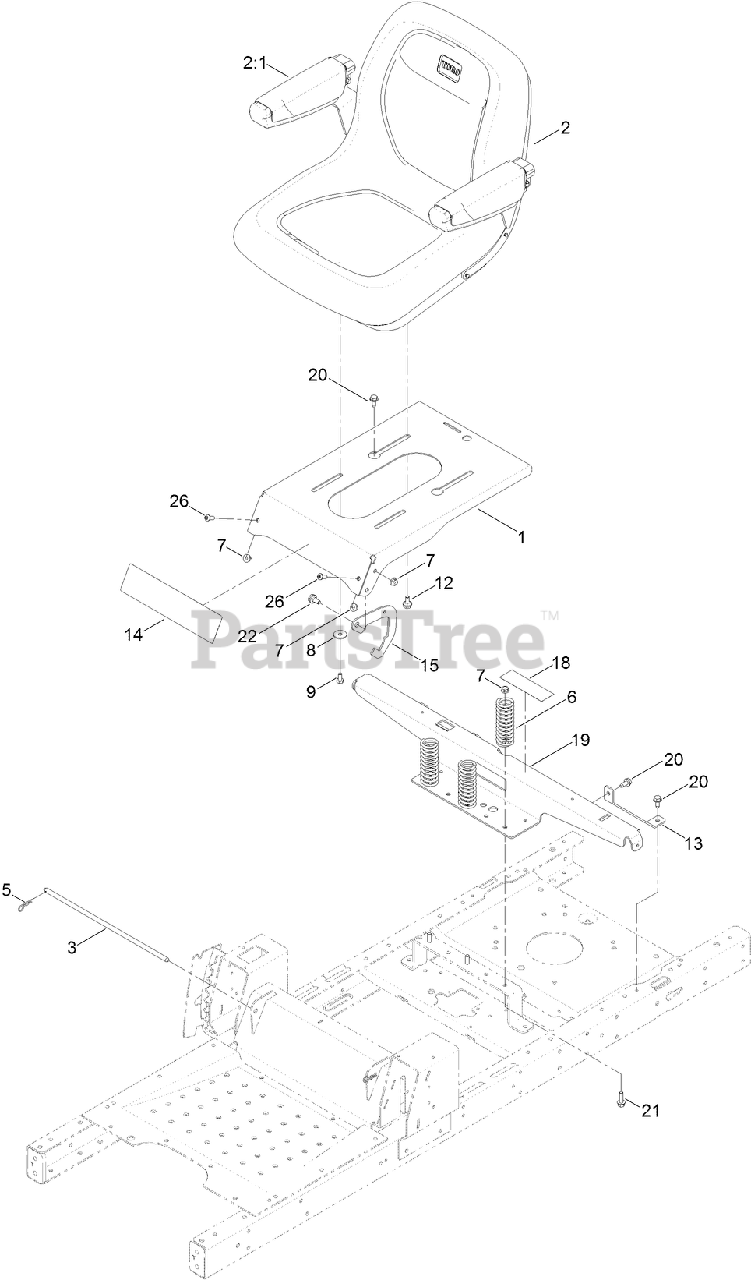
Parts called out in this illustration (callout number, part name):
1	PAN-SEAT
2	SEAT-18 INCH
3	ROD-PIVOT, NARROW
5	PIN-COTTER
6	SPRING-COMPRESSION
7	NUT-HF, NI
8	WASHER-PIVOT
9	SCREW-HH
12	BOLT-SHOULDER,HFH
13	SUPPORT-TANK, REAR
14	DECAL-TIMECUTTER
15	LATCH-SEAT
18	DECAL-SERVICE, CE
19	SUPPORT-POD
20	SCREW-HWHTF
21	SCREW-HHF
22	BOLT-SHOULDER,HFH
26	SCREW-HSBH
